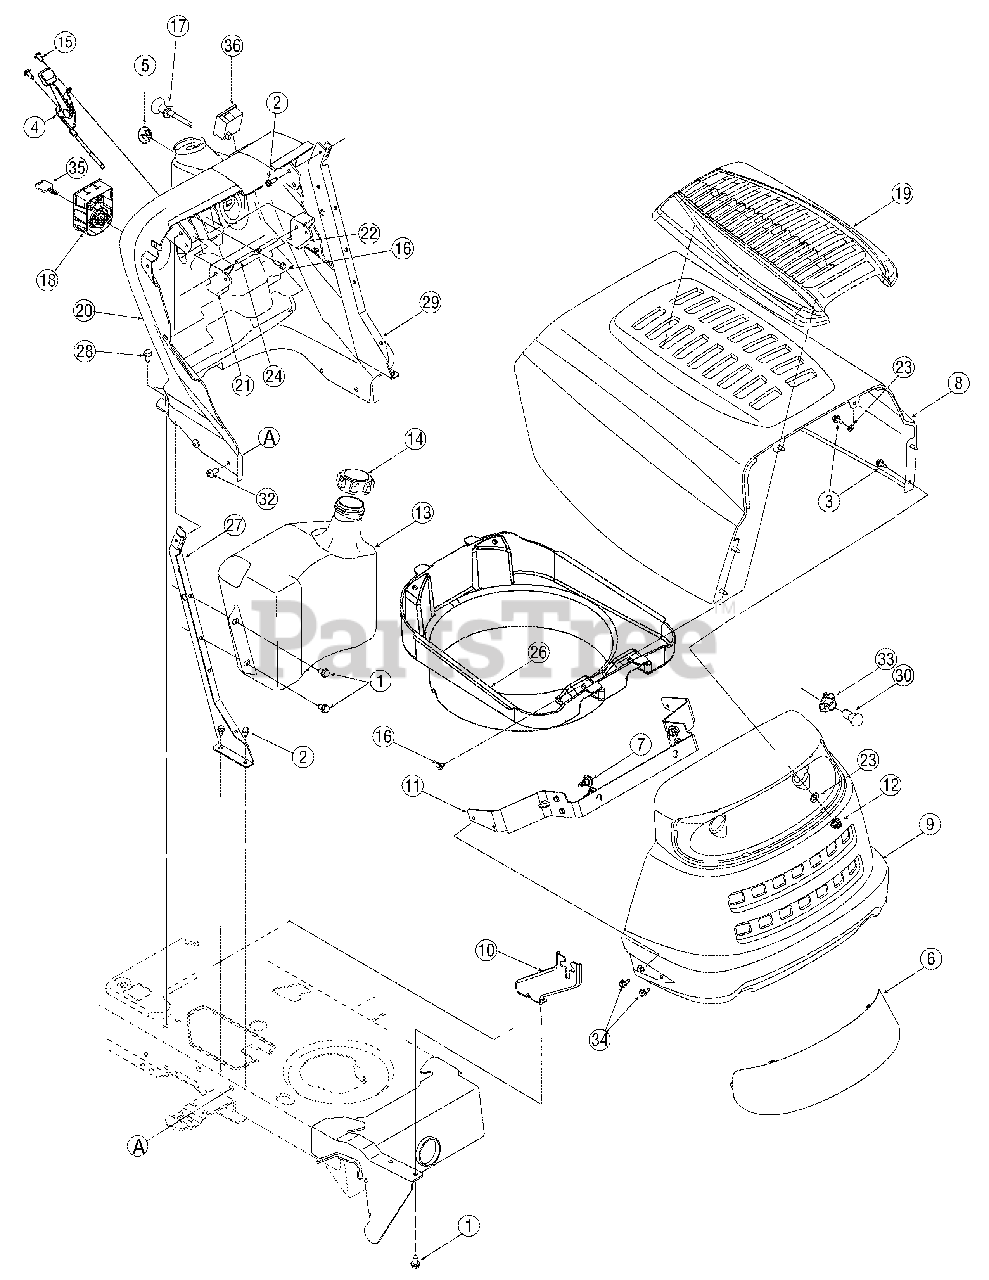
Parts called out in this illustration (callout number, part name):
1	Screw, 5/16-12 x .750
2	Self-tapping Screw, 1/4-20 x.5
3	Hex Cap Screw, 1/4-20 x.62
4	Throttle/Choke Control Cable
4	Throttle Control/Cable
5	Choke Plug
6	Headlight Lens
7	Shoulder Screw,.43 x.29
13	Fuel Tank, Two Gallon
13	Fuel Tank, Three Gallon
14	Fuel Cap
15	Screw, 1/4-14 x.625
16	Self-tapping Screw, 1/4-15 x.75
17	Choke Control Cable
18	Ignition Switch
19	Hood Cover, 5 Style
20	Dash Panel
21	Cruise Control Button
22	Parking Brake Button
23	Flat Washer, .265 x .938 x 1.20
24	Brake/Cruise Pivot Rod
26	Plenum, Kohler Twin
26	Plenum, Kohler Courage Single
30	Lamp
31	Bell Washer,.265 x.75 x.062
32	Screw, 5/16-18 x.75
33	Headlight Socket
34	Hex Index Screw, 1/4-20 x.625
35	Ignition Key w/ plastic cover
35	Ignition Key w/o plastic cover
36	Systems Ind. Monitor w/Hr. Mtr.
36	Systems Ind. Monitor w/ Amtr.
